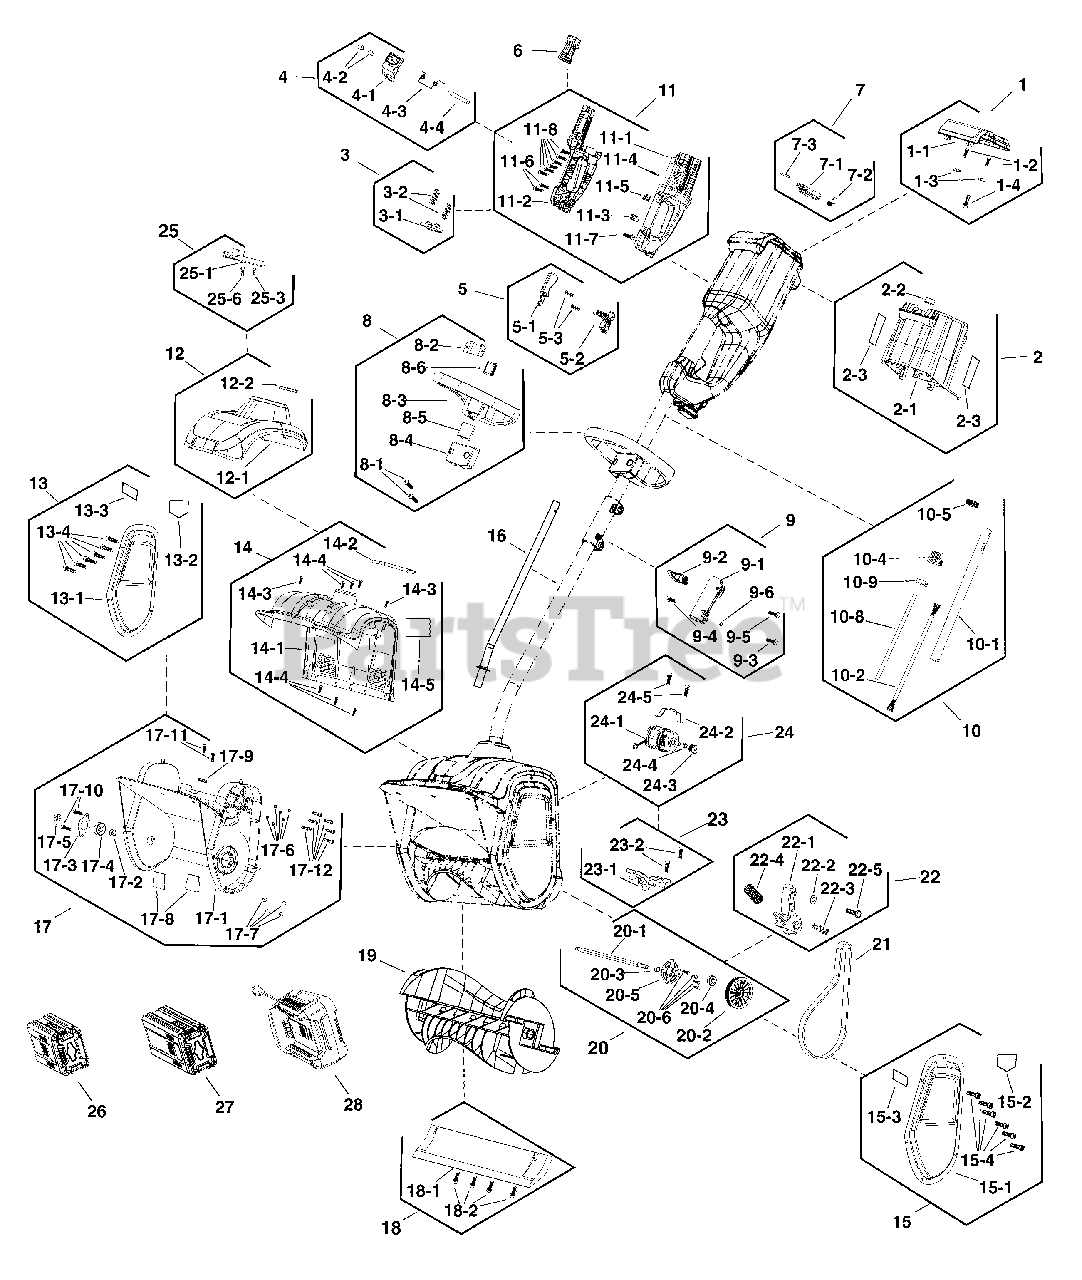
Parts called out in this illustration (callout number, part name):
1	KIT, BATTERY COVER
1-1	BATTERY COVER
1-3	PIN
2	KIT, HANDLE COVER
2-1	HANDLE COVER
2-2	MAGNET
2-3	LABEL
3	KIT, BATTERY SPRING
3-1	SPRING SEAT
3-2	COMPRESSED SPRING
4	KIT, BATTERY RELEASE
4-1	BATTERY RELEASE BUTTON
4-2	AXLE SLEEVE
4-3	SPRING
4-4	PIN
5	KIT, SWITCH
5-1	TRIGGER SWITCH
5-2	LOCK-OUT BUTTON
5-3	LOCK-OUT SPRING
6	SET, Key
7	KIT, KEY COVER
7-1	KEY COVER
7-2	KEY COVER TORSION SPRING
7-3	CYLINDRICAL PIN
8	KIT, AUXILIARY HANDLE
8-2	CLAMP
8-3	AUXILIARY HANDLE
8-4	AUXILIARY HANDLE COVER
8-5	RUBBER RING
8-6	PAD
9	KIT, COUPLING
9-1	PIPE
9-2	ROTARY KNOB
9-4	BOLT
9-6	SPRING WASHER
10	KIT, HARNESS
10-1	UPPER PIPE
10-2	FIVE-CORE CABLE
10-4	CHARGER, SOCKET
10-5	SWITCH
10-9	CLIP
11	KIT, HANDLE
11-1	LEFT HANDLE
11-2	RIGHT HANDLE
11-4	KEY HOLDER PLATE
11-5	80V FEMALE INSERT
11-6	ST4.2-30 SCREW
11-8	ST4.2-16 SCREW BLACK
12	KIT, CAP
12-1	RAIN CAP
12-2	SEAL RING
13	KIT, LEFT COVER
13-1	LEFT SIDE COVER
13-2	WARNING LABEL
13-3	LABEL
14	KIT, UPPER HOUSING
14-1	UPPER HOUSING
14-2	SEALING STRIP
14-4	ST4.2-16 SCREW BLACK
14-5	LABEL
15	KIT, RIGHT COVER
15-1	RIGHT SIDE COVER
15-2	WARNING LABEL
15-3	LABEL
16	KIT, LOWER TUBE
17	KIT, LOWER HOUSING
17-1	LOWER HOUSING
17-3	BEARING PLATE
17-4	BEARING
17-5	NUT
17-6	SPRING WASHER
17-8	SPONGE
17-9	CLAMP
17-11	ST4.2-16 SCREW BLACK
17-12	SCREW M5-10
18	KIT, SCRAPER
18-2	ST4.2-16 SCREW BLACK
19	KIT, AUGER
20	KIT, IMPELLER SHAFT
20-1	IMPELLER SHAFT
20-2	BELT PULLEY
20-4	BEARING
20-5	BEARING FIXED PLATE
21	KIT, BELT
22	KIT, TENSION PULLEY
22-1	TENSION PULLEY
22-2	GASKET
22-3	SPRING
22-4	COMPRESSED SPRING
23	KIT, MOTOR SUPPORT
23-1	MOTOR SUPPORT
23-2	ST4.2-16 SCREW BLACK
24	KIT, MOTOR
24-1	MOTOR
24-2	BRACKET
24-4	MOTOR GASKET
24-5	ST4.2-16 SCREW BLACK
25	KIT, PCB
25-1	PCB
25-6	ST4.2-16 SCREW BLACK
26	BATTERY, 2AH, NA
27	BATTERY, 4AH, NA
28	CHARGER, RAPID, NA
